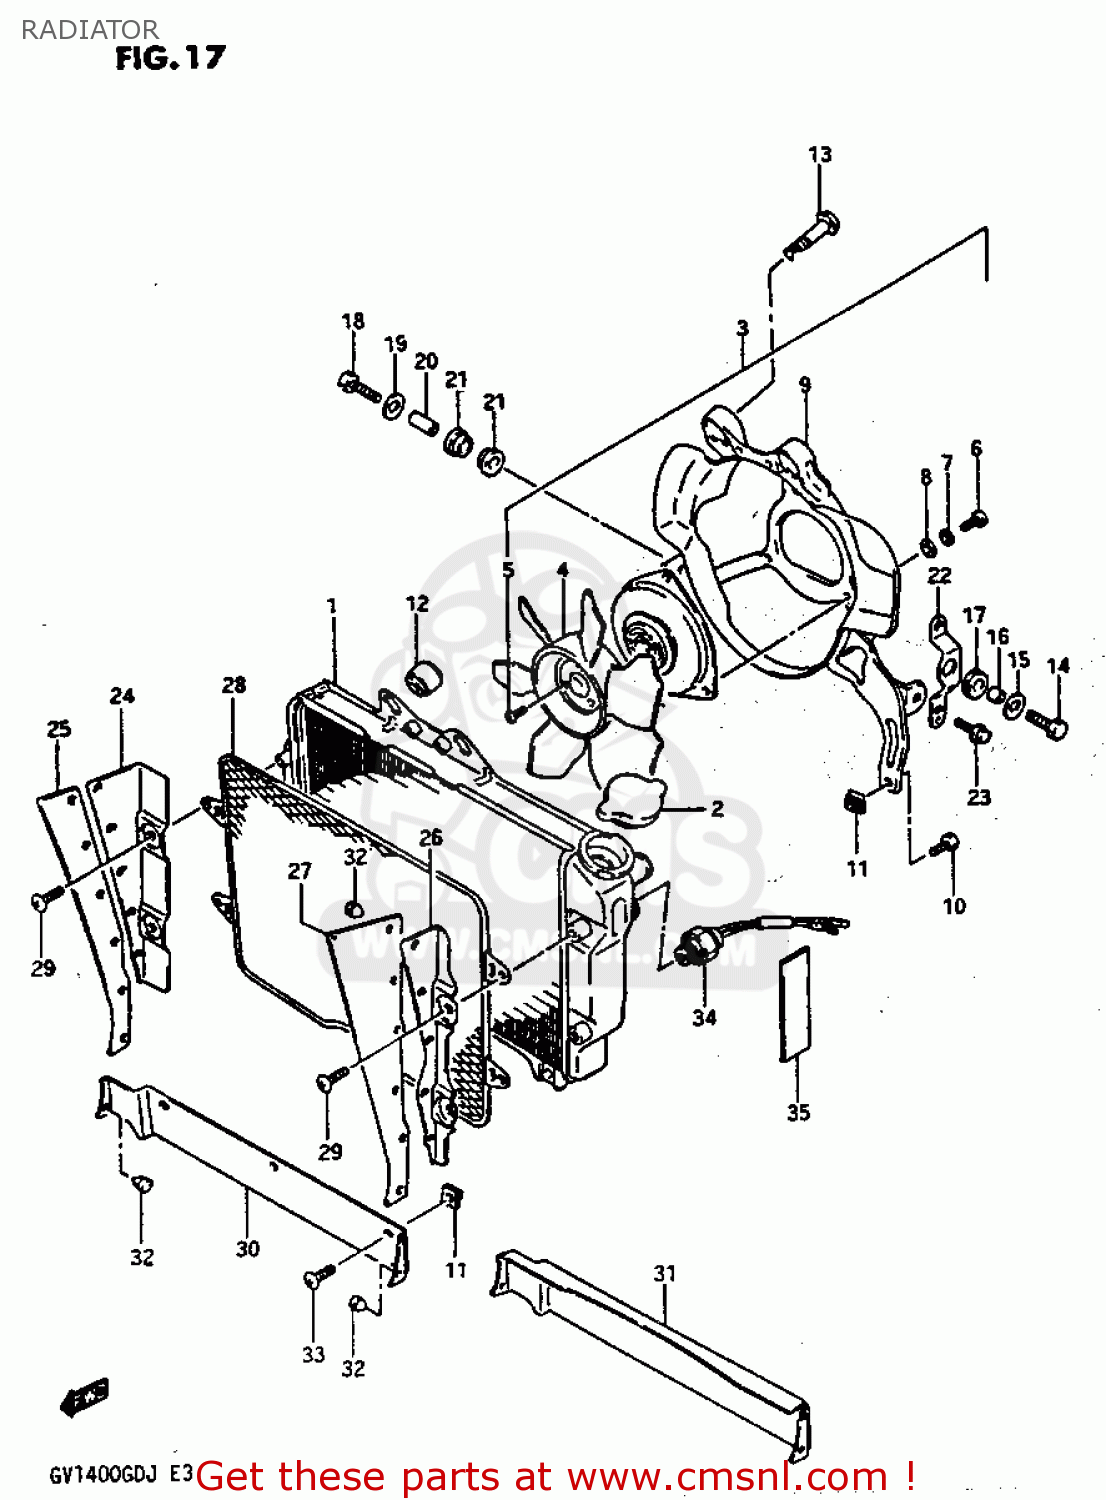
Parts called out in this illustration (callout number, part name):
1	RADIATOR,WATER
2	CAP,RADIATOR
3	FAN ASSEMBLY,RADIATOR
4	FAN
5	BOLT
6	SCREW 5X10
7	LOCK WASHER
8	WASHER
9	SHROUD
10	BOLT,RADIATOR FAN
11	NUT,RADIATOR
12	CUSHION,RADIATOR NO.1
13	BOLT
14	BOLT
15	WASHER
16	SPACER (7X9X7)
17	CUSHION
18	BOLT(6X35)
19	WASHER(6,5X22X1.6)
20	SPACER (6.4X9X20)
21	CUSHION
22	BRACKET COMP,RADIATOR
23	BOLT 6X16
24	PLATE,RADIATOR,RIGHT
25	SEAL,RADIATOR,RIGHT
26	PLATE,RADIATOR,LEFT
27	COVER,RADIATOR
28	NET,RADIATOR
29	SCREW
30	COVER,RADIATOR,LOWER
31	COVER,RADIATOR,LOWER
32	CUSHION
33	SCREW
34	SWITCH
35	COVER,FAN SWITCH
